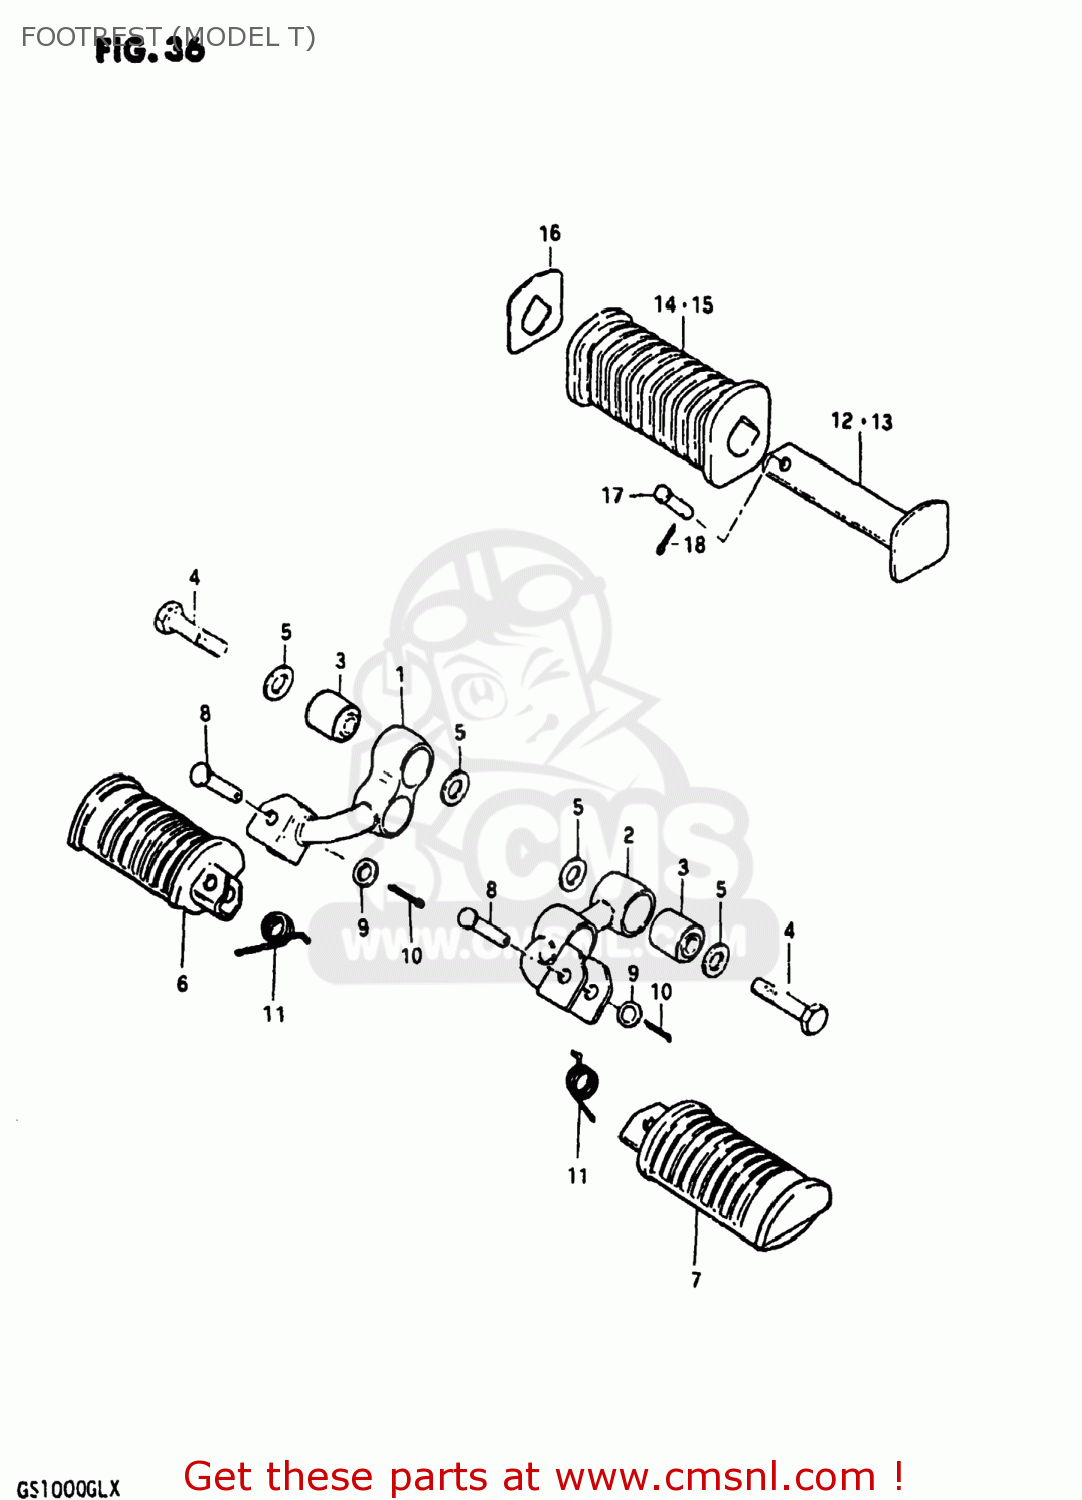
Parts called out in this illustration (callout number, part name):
1	BAR,FRONT FOOTREST,RIGHT
2	BAR,FRONT FOOTREST,LEFT
3	BUSH
4	BOLT
5	WASHER (10.1X21X2.3)
6	RUBBER,FRONT FOOTREST
7	FOOTREST
8	PIN
9	WASHER
10	PIN
11	SPRING
12	BAR,REAR FOOTREST
13	BAR,REAR FOOTREST
14	RUBBER,PILLION FOOTREST
15	RUBBER, LH
16	WASHER,REAR FOOTREST RUBBER
17	PIN
18	PIN
